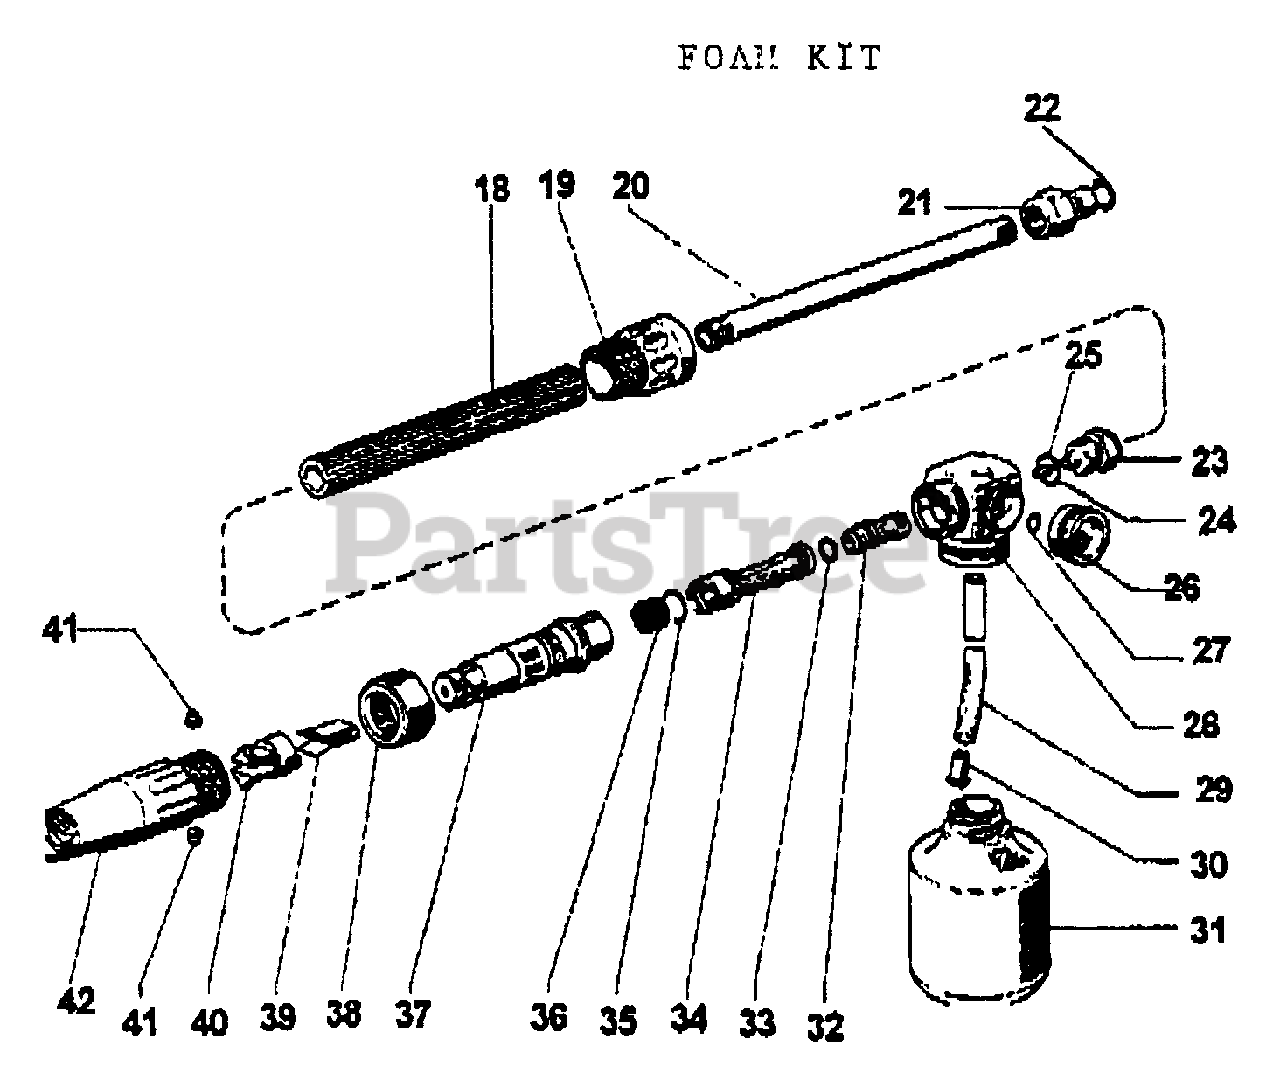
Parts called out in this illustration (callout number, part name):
18	GRIP, HANDLE
19	RINGNUT
20	TUBE
21	COUPLING - MALE
22	O-RING - .359 X .103
23	NIPPLE
24	NOZZLE - RED
25	O-RING - .614 X .070
26	KNOB, REGULATING
27	O-RING
28	BODY
29	TUBE
30	FILTER
31	CONTAINER, 5 LITER
32	TUBE
33	O-RING
34	TUBE
35	O-RING, .489 X.070
36	FILTER
37	CYLINDER
38	NUT
40	HOLDER, BLADE
41	CAP
42	KNOB, REGULATING
